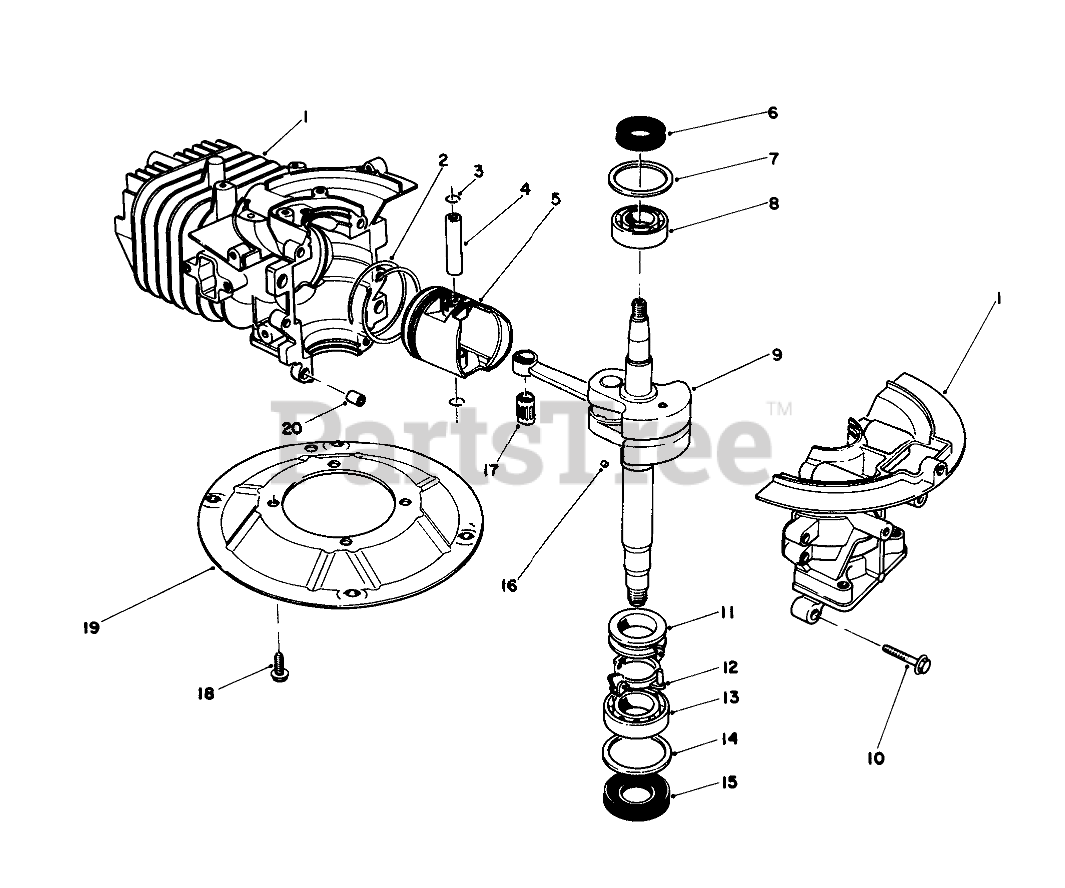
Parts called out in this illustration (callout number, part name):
1	CRANKCASE
2	RING SET
4	PIN-PISTON
5	Piston
6	OIL SEAL
7	WASHER-UPPER
8	BEARING-UPPER
9	CRANKSHAFT
11	SPACER
12	BRACKET
13	LOWER BRG
14	WASHER-LOWER
15	SEAL-OIL
17	BEARING
19	PLATE-MOUNTING
